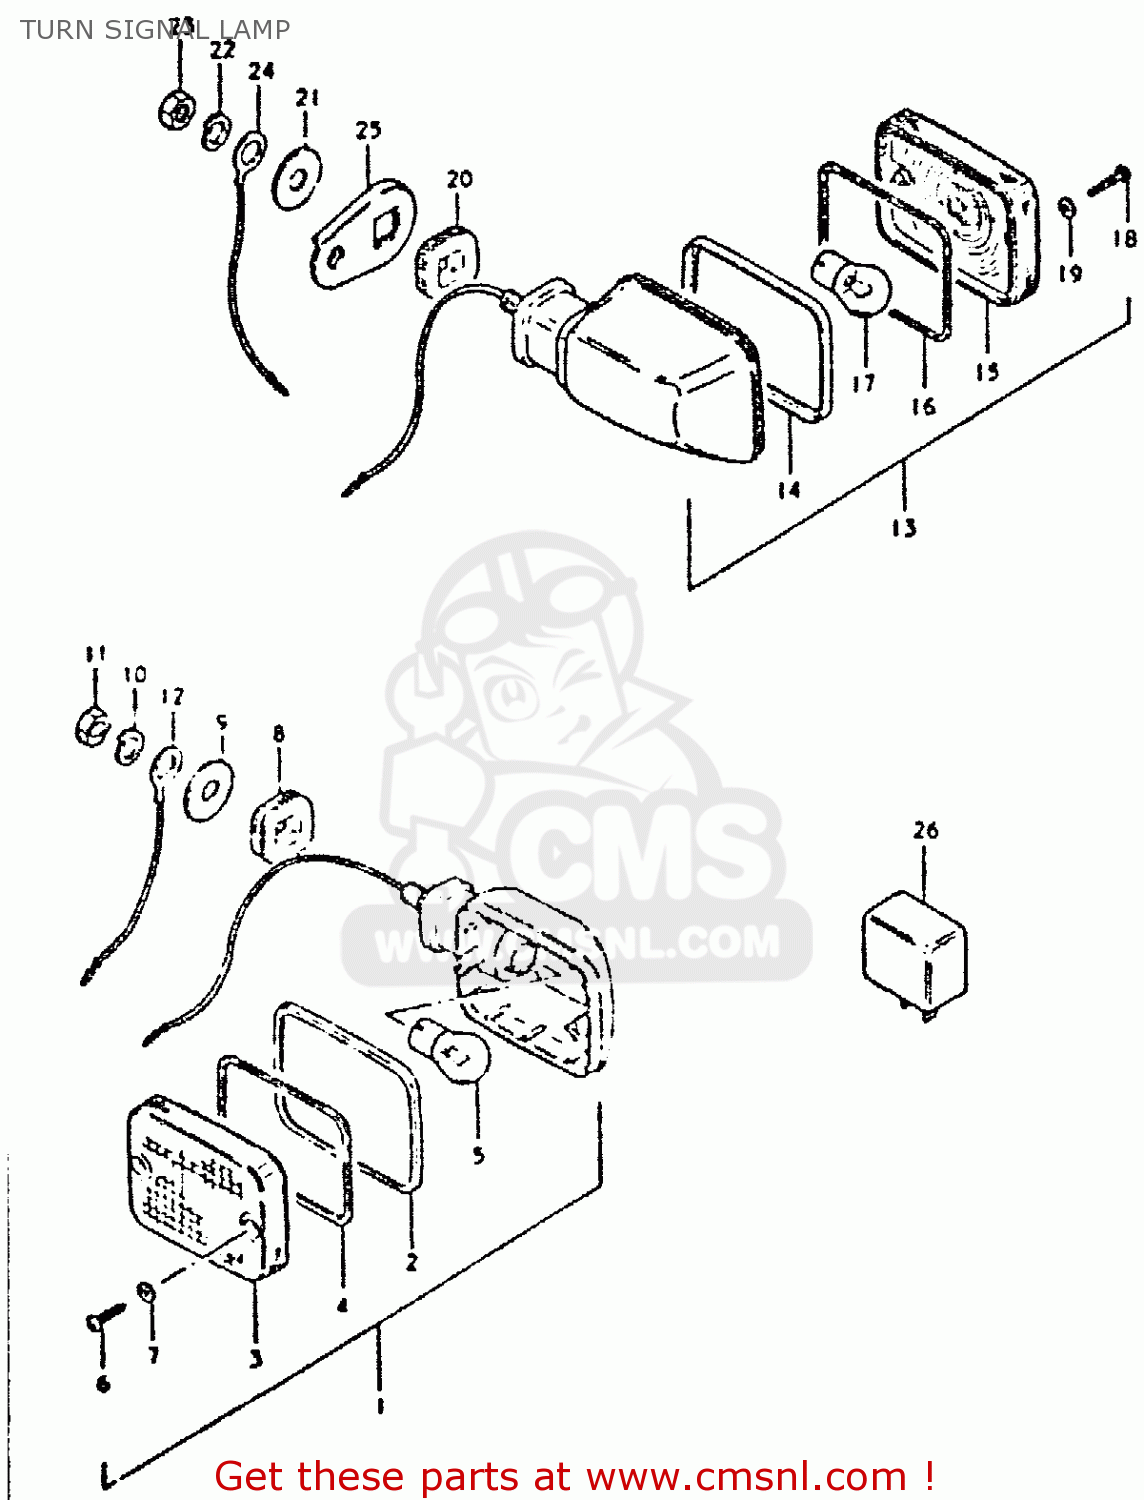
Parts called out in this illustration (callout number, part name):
1	LAMP, FRONT TURN SIGNAL
2	RIM
3	LENS
4	GASKET (NAS)
5	BULB 12V 21W
6	SCREW
7	GASKET (NAS)
8	CUSHION
9	WASHER (10.5X30X2.3)
10	LOCK WASHER
11	NUT
12	LEAD WIRE,EARTH
13	LAMP, REAR TURN SIGNAL
14	RIM
15	LENS
16	GASKET (NAS)
17	BULB 12V 21W
18	SCREW
19	GASKET (NAS)
20	CUSHION
21	WASHER (10.5X30X2.3)
22	LOCK WASHER
23	NUT
24	LEAD WIRE,EARTH
25	BRACKET,RR TURN SIGNAL LAMP
26	RELAY,TURN SIGNAL
